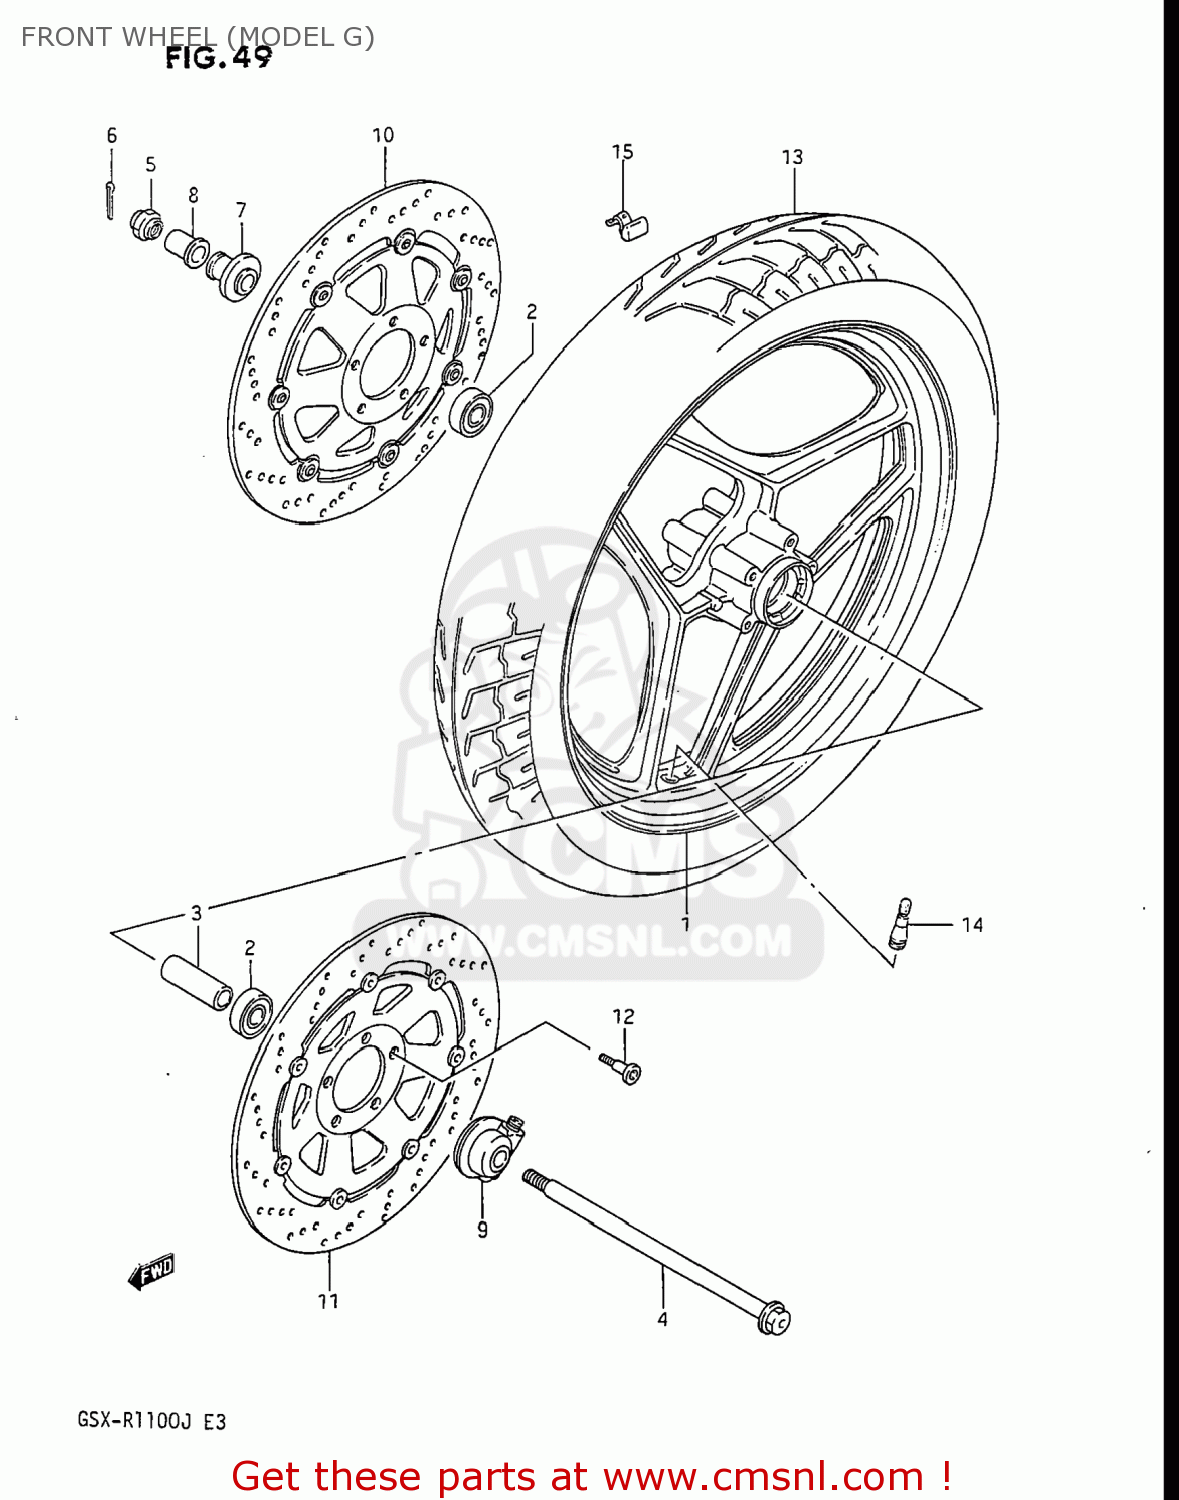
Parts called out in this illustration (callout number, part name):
1	WHEEL,FRONT (MT2.75X18)
2	BEARING
3	SPACER(15.3X21.7X77)
4	AXLE,FR
5	NUT (12MM)
6	COTTER PIN
7	SPACER,FR HUB BEARING,R
8	SPACER
9	BOX ASSEMBLY,SPEEDOMETER GEAR
10	DISC,BRAKE
11	DISC,BRAKE
12	BOLT
13	TIRE,TUBELESS 110/80V
14	VALVE,TIRE
15	BALANCER,WHEEL
